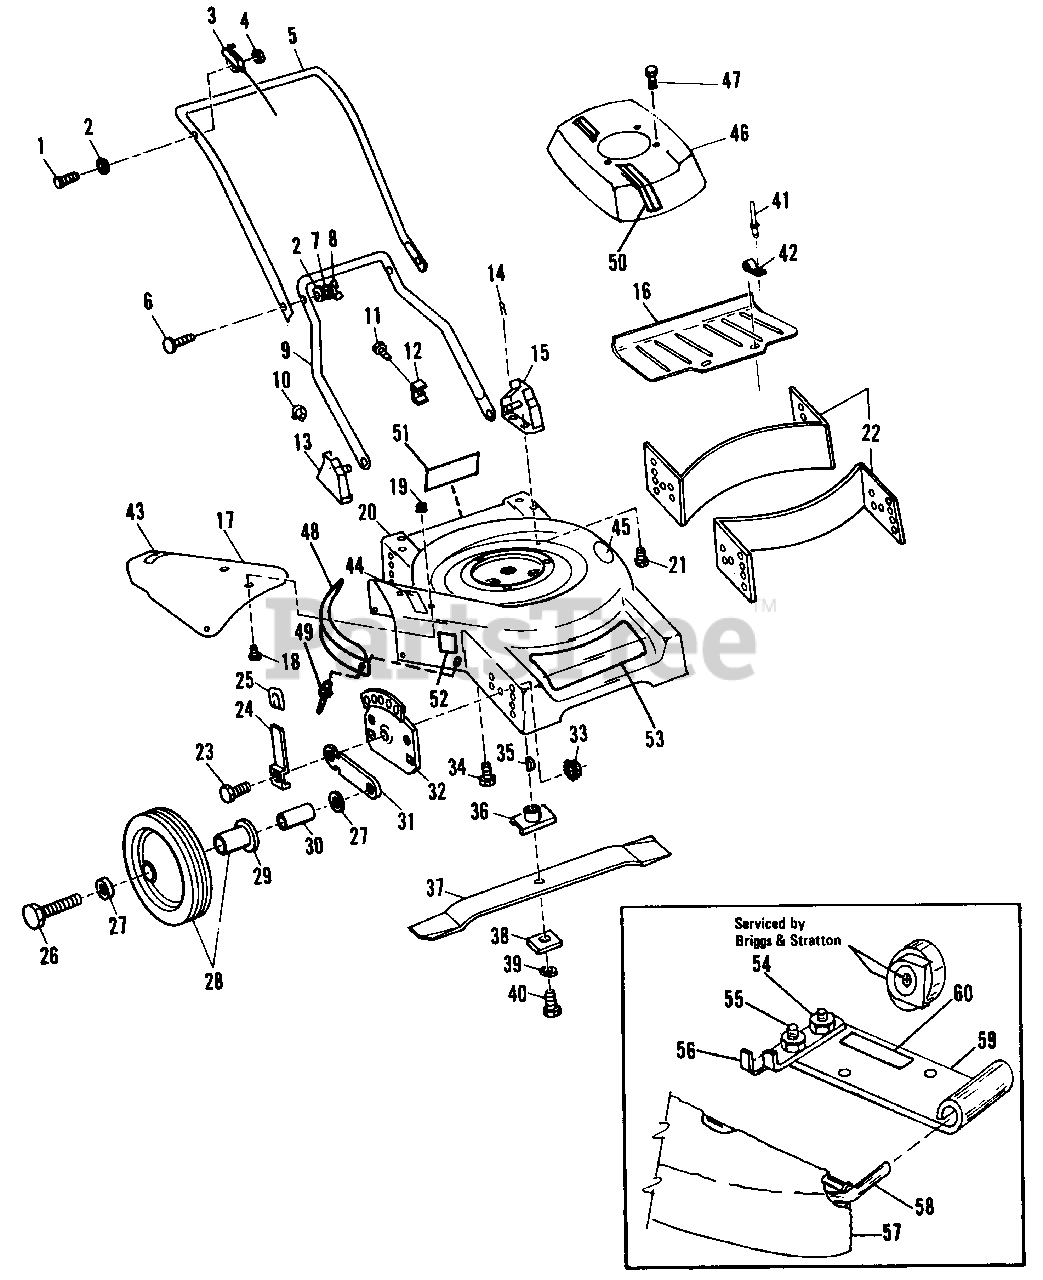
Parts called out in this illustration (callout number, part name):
1	BOLT, Throttle
2	WASHER, Curved
3	CONTROL, Throttle
4	NUT, Throttle
5	HANDLE, Folding
6	BOLT, Handle
8	NUT, Wing
9	YOKE
10	CLAMP, Throttle
11	SCREW, Casing
12	CLAMP, Casing
13	BRACKET ASSY, RH
14	CLIP, Hairpin
15	BRACKET ASSY, LH
16	TRAILGUARD
17	EXTENSION, Chute
18	BOLT, Carriage
19	NUT, Keps
20	HOUSING
21	BOLT, 1/4-20 x 5/8
22	BAFFLE
23	BOLT, Shoulder QWA
24	SPRING, QWA
25	TIP, QWA
26	BOLT, Axle
27	WASHER, 3/8 Flat
28	WHEEL ASSY, w/Bearing 8"
28	WHEEL ASSY, w/Bearing 7"
29	BEARING, Wheel
30	SPACER, Wheel
31	ARM, QWA
32	PLATE, Wheel Adj.
33	NUT, Baffle
34	SCREW, Engine
35	KEY, Engine Shaft
36	ADAPTOR ASSY, Blade
37	BLADE
38	SPACER, Blade Adaptor
39	WASHER, Blade
40	BOLT, Blade
41	RIVET, Pop
43	DECAL, "Caution"
44	DECAL, "Danger . . . "
45	DECAL, "Place Foot Here . . ."
46	SHROUD
47	SCREW, Shroud
48	GUARD, Blade
49	RIVET, 1/4" Pop
50	DECAL, Shroud Stripe
51	DECAL, Simplicity 6"
52	DECAL, 21"
52	DECAL, 19"
53	DECAL, Deck, Simplicity
54	NUT, Throttle
55	BOLT, Rd. Hd.
56	BRACKET
57	GRASS BAG
58	FRAME ASSY
59	PLATE
60	BOLT, 3/8-16 x 2-1/2
60	DECAL, Caution
